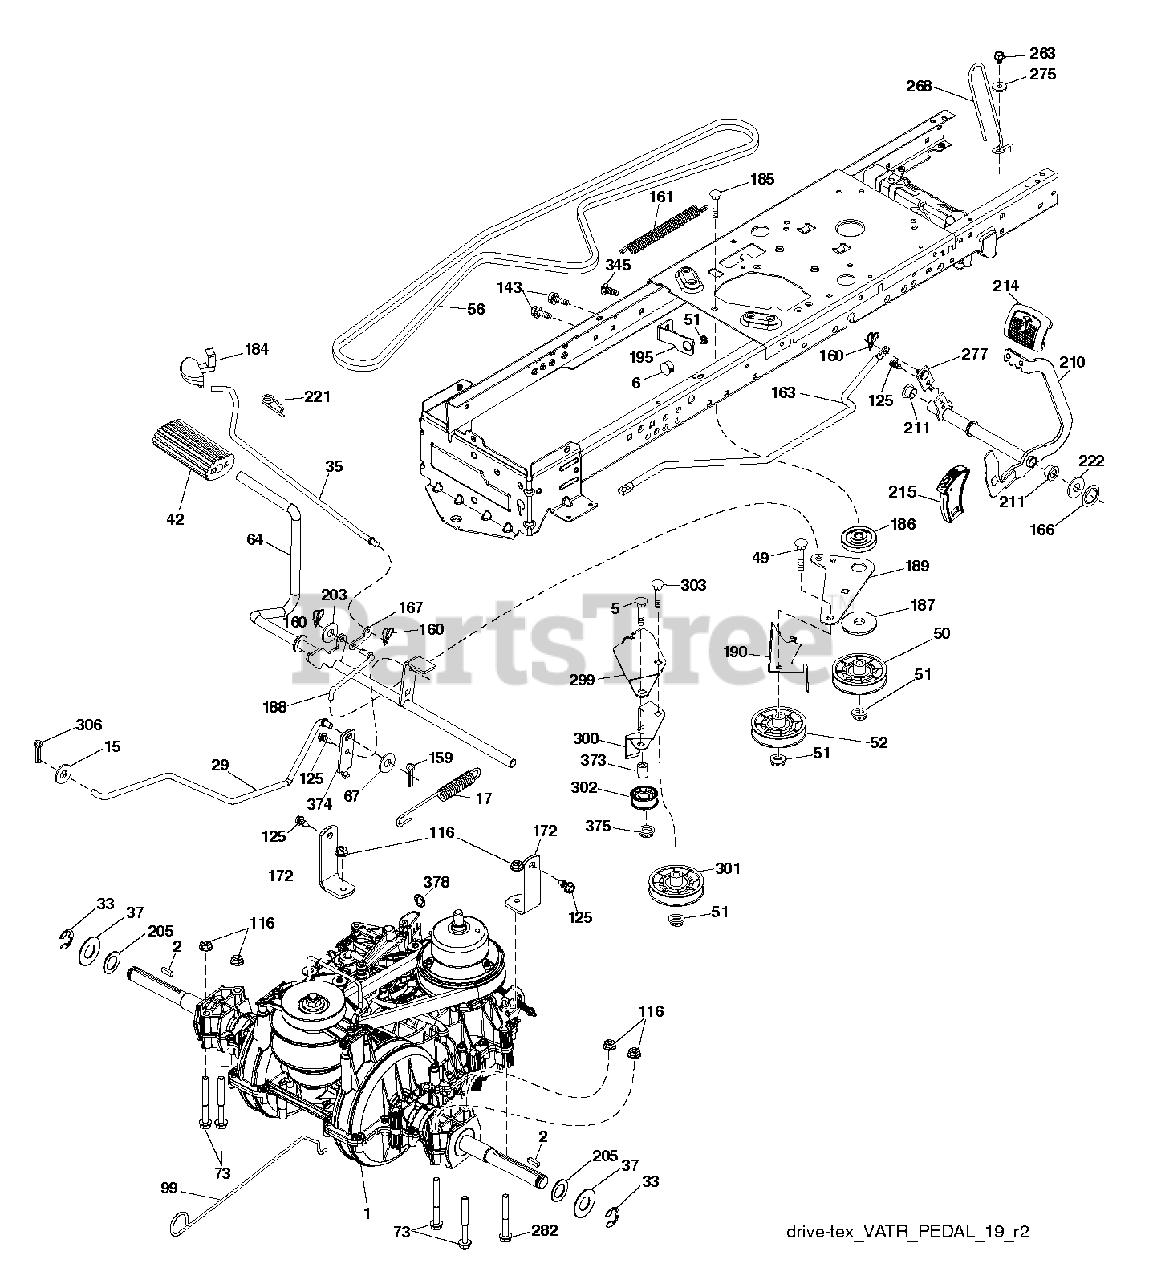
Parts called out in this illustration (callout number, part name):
2	SQUARE KEY
6	BUSHING.SNAP.NYL.BLK.
15	WASHER
17	SPRING BRAKE VARIATOR
29	BRAKE.VARIATOR.SD3
35	ROD.CNTRL.PARK.PREDATOR.LT.TEX
37	WASHER.HARDENED
42	PEDAL COVER T
50	IDLER.FLAT.910.OFFSET
51	NUT LOCK FLG 3/8-16 UNC
52	IDLER.V-GROOVE.910.OFFSET
56	BELT.V.EURO.VARIATOR
64	SUBASM.SHAFT.PEDAL.BRAKE
67	WASHER
99	ROD.BYPASS.VARIATOR.GEN2
116	NUT LOCK HEX FLANGE 5/16-18
125	SCREW
143	SCREW LT
159	COTTER PIN
160	RETAINER CLIP
161	SPRING, RETURN LT
163	ROD.CONTROL.PEDAL.VARIATOR
166	NUT.PUSH.625
167	LATCH.BRAKE.SPRING
172	STRAP.TORQUE.VARIATOR
184	HANDLE.PARKNG BRK.PRED.LT.428
186	SPACER.RETAINER
187	WASHER 12/32X2X10GA
188	RP LINK.CLUTCH.GROUND.DRIVE
189	BELLCRANK.GROUND.DRIVE.TEX.
190	KEEPER.BELLCRANK.DRIVE
195	BRACKET.BRAKE.BRAKE.VAR.SD
203	WASHER
210	WELDMENT.PEDAL.VARIATOR
211	BEARING.NYLON
214	PEDAL.FORWARD.PAD.TEX
215	CAP.PEDAL.REVERSE.VARIATOR
221	RETAINER.SPRING.CLIP.H
222	WASHER 21/32 X 1-1/4 X 10 GA.
263	SCREW, 3/8-16X3/4
268	GUARD MUFFLER
275	WASHER
277	SUBASM.LINK.ROCKER.PEDAL
282	BOLT HEX FLGHD 5/16-18X3 GR. 5
299	BRACKET.MOUNT.IDLERS
300	KEEPER.IDLERS.REAR.VARIATOR
301	PULLEY.IDLER.V-GROOVE
302	PULLEY.IDLER.FLAT.2"
303	BOLT CARRIAGE
306	PIN COTTER
373	SPACER.IDLER
374	ARM.CONTROL.BRAKE
378	NUT.PUSH.8MM
